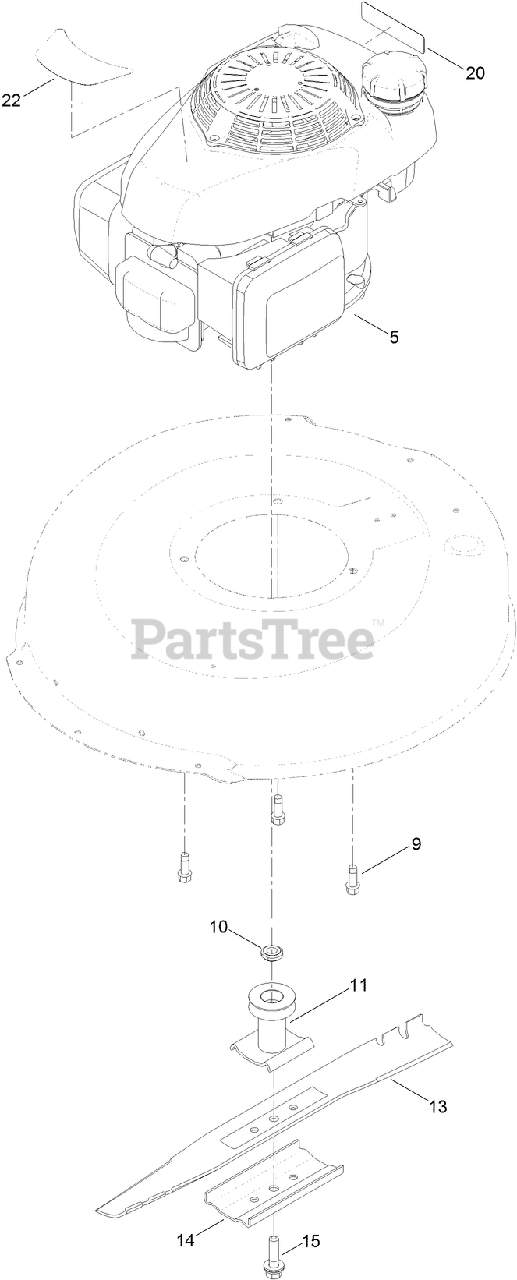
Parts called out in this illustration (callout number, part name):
9	SCREW-TAPTITE
10	SPACER-DRIVER
11	DRIVER-BLADE
14	SUPPORT-BLADE
15	BOLT-BLADE
20	DECAL-ARRESTER, SPARK
22	DECAL-SHROUD, HONDA
